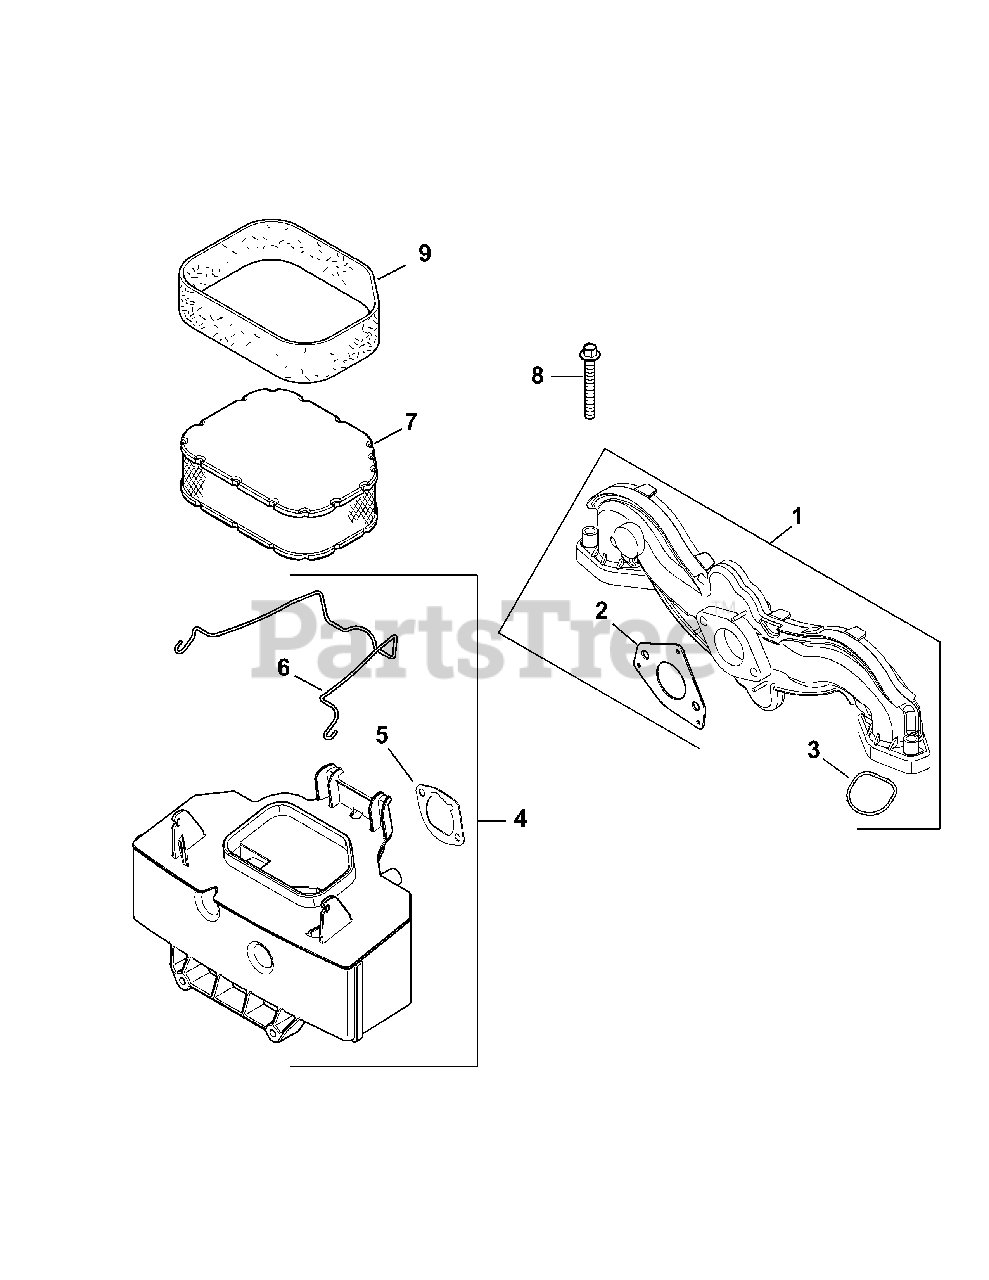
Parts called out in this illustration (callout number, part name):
1	Manifold, Intake
2	Gasket, Carburetor
3	O-Ring, Intake Port
4	Kit, Air Cleaner Base
5	Gasket, Air Cleaner Base
6	Latch, Air Cleaner Element
7	Element, Air Filter
8	Screw, FLG M6 x 1.0 x 40
9	Element, Pre-Cleaner
